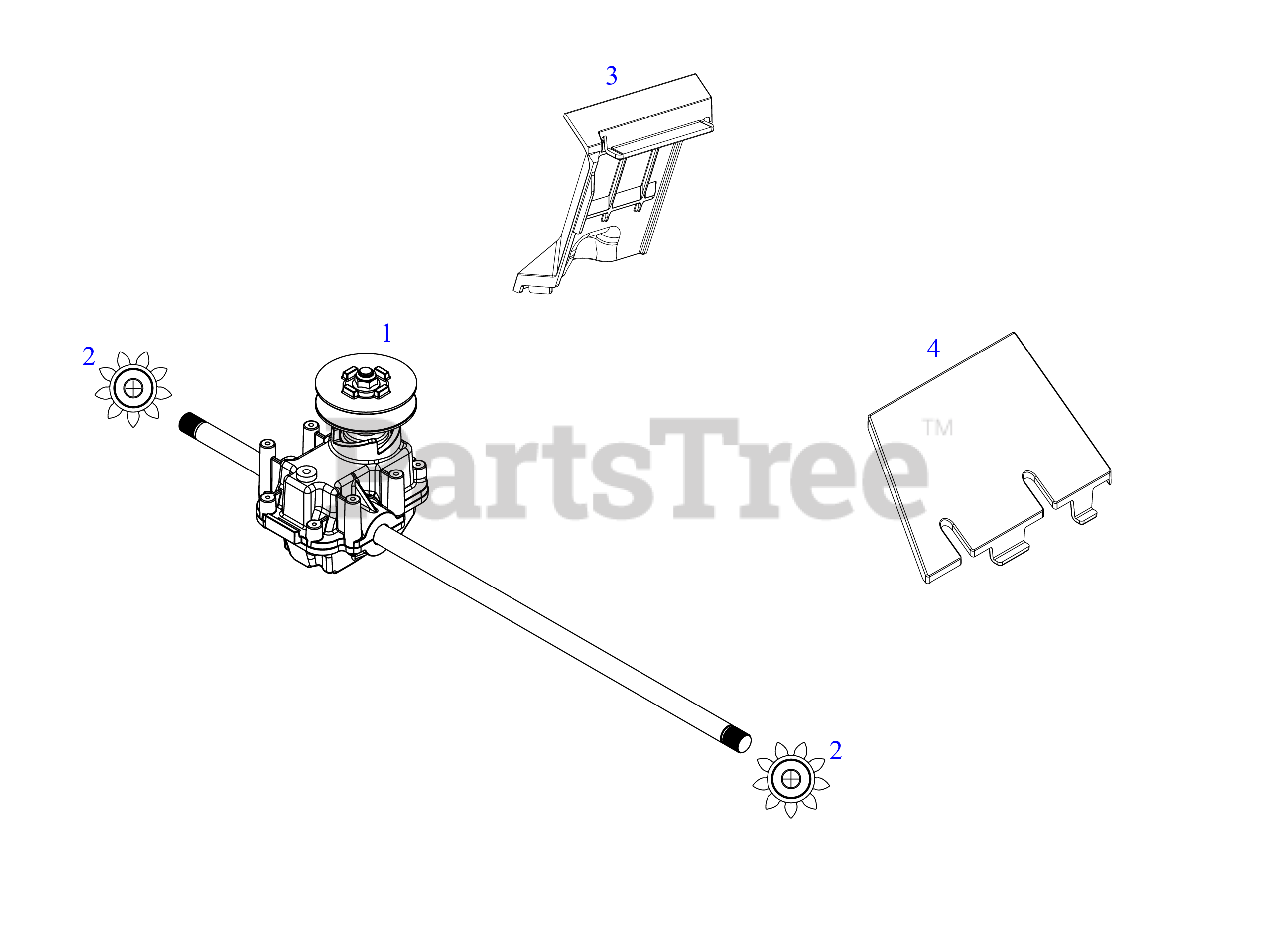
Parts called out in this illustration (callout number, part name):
1	TRANSMISSION
2	SPUR GEAR 9T
3	TRANSMISSION COVER (FRONT)
4	TRANSMISSION COVER (REAR)
